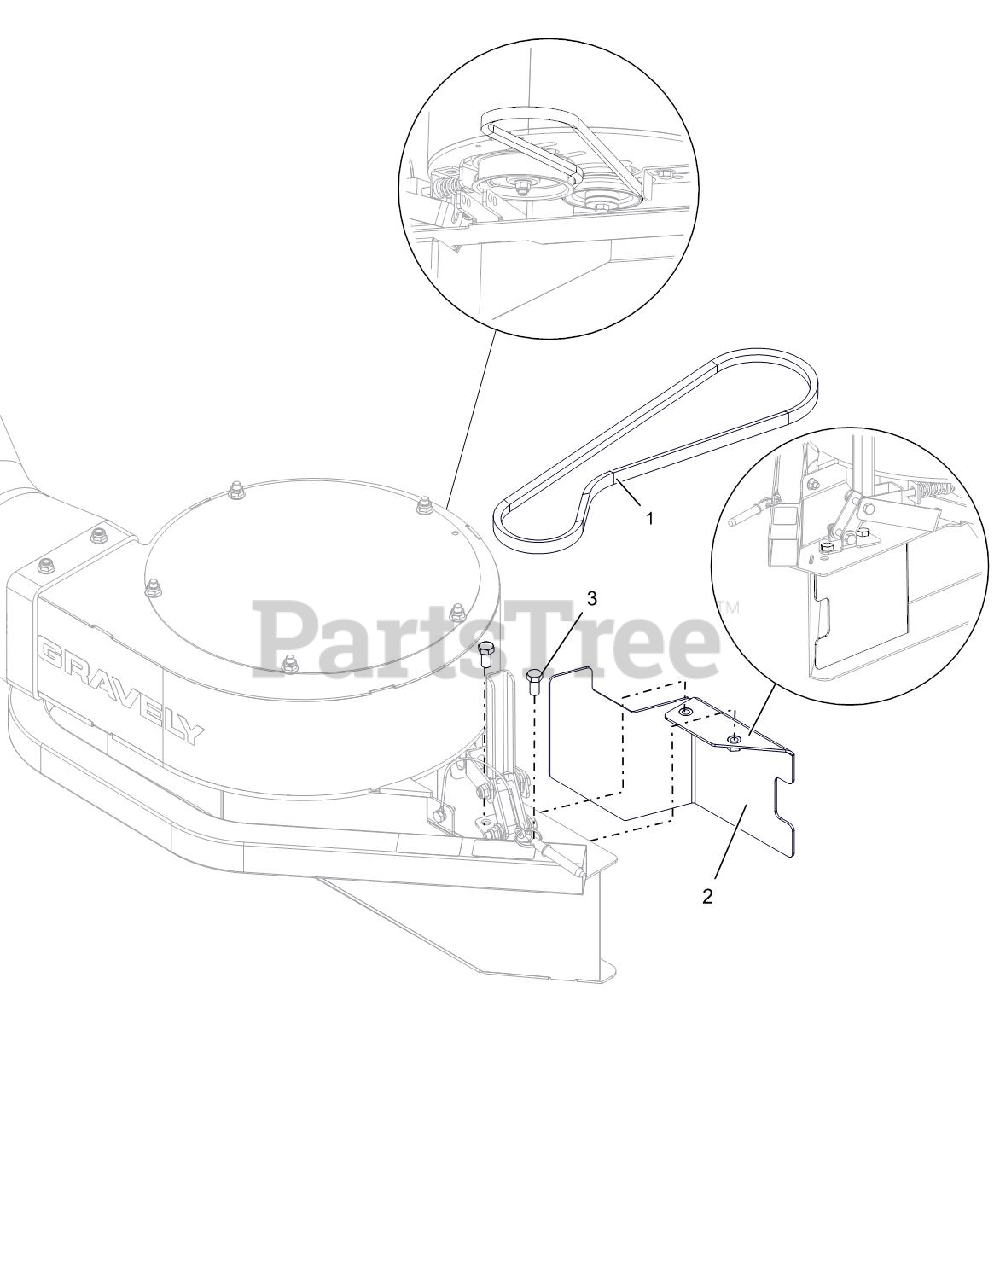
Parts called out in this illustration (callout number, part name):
1	V-BELT, 4L WRAPPED CLUTCHING
2	52" FRT BLOWER BAFFLE WMT -BLK
3	@BLT-HEX .38-16X.75 GR5 YWZC
